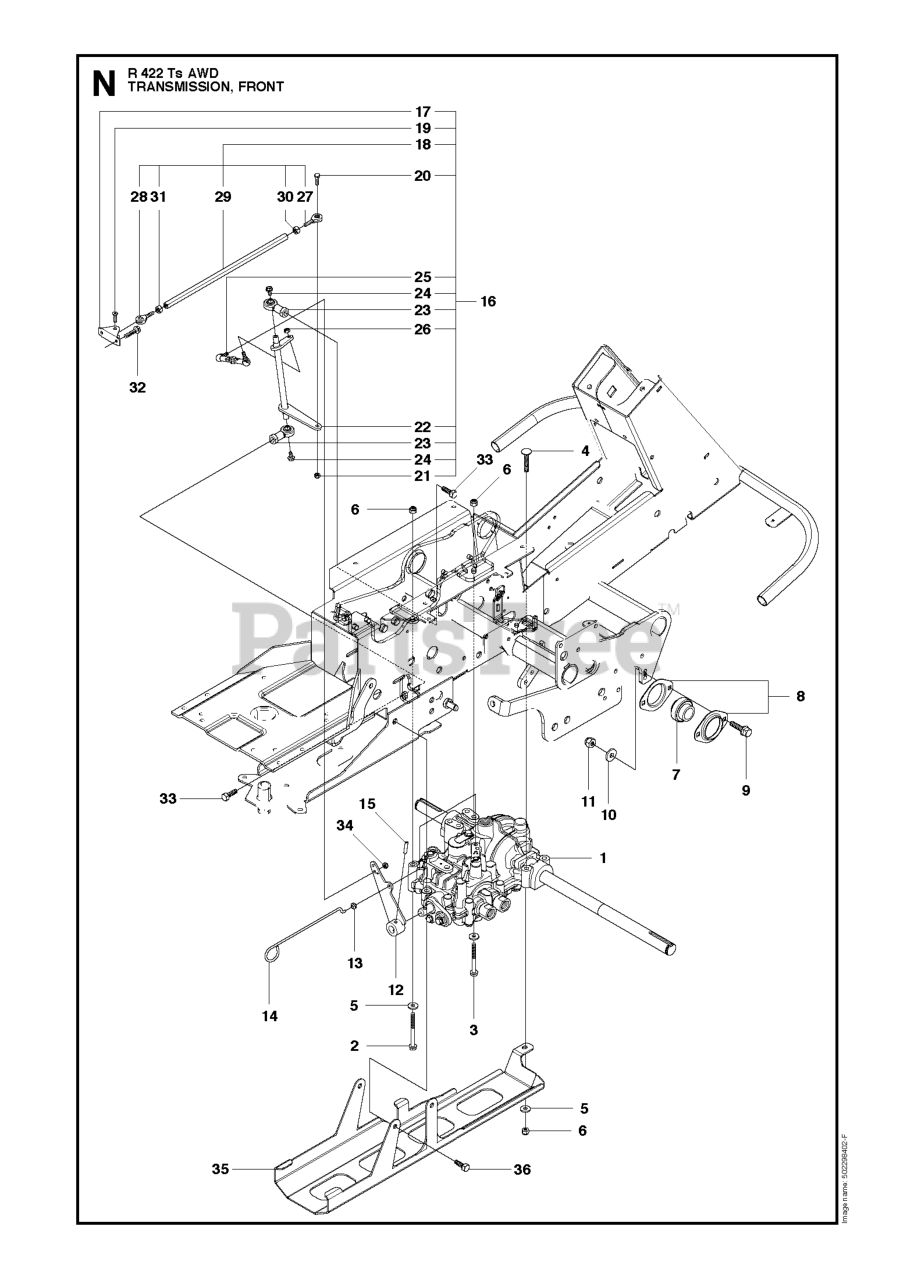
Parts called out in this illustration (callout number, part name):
1	TRANSMISSION
5	WASHER BRB 8.4X17
6	LOCKNUT M8
8	BEARING HOUSING
9	BOLT
10	WASHER BRB 8.4X17
11	LOCKNUT M8
13	FUEL TANK BUSHING
21	NUT FLANGE - M6
24	SCREW EHHFM
25	ADJUSTING ROD
26	NUT FLANGE - M6
33	Screw M10x25
34	LOCKNUT M6
